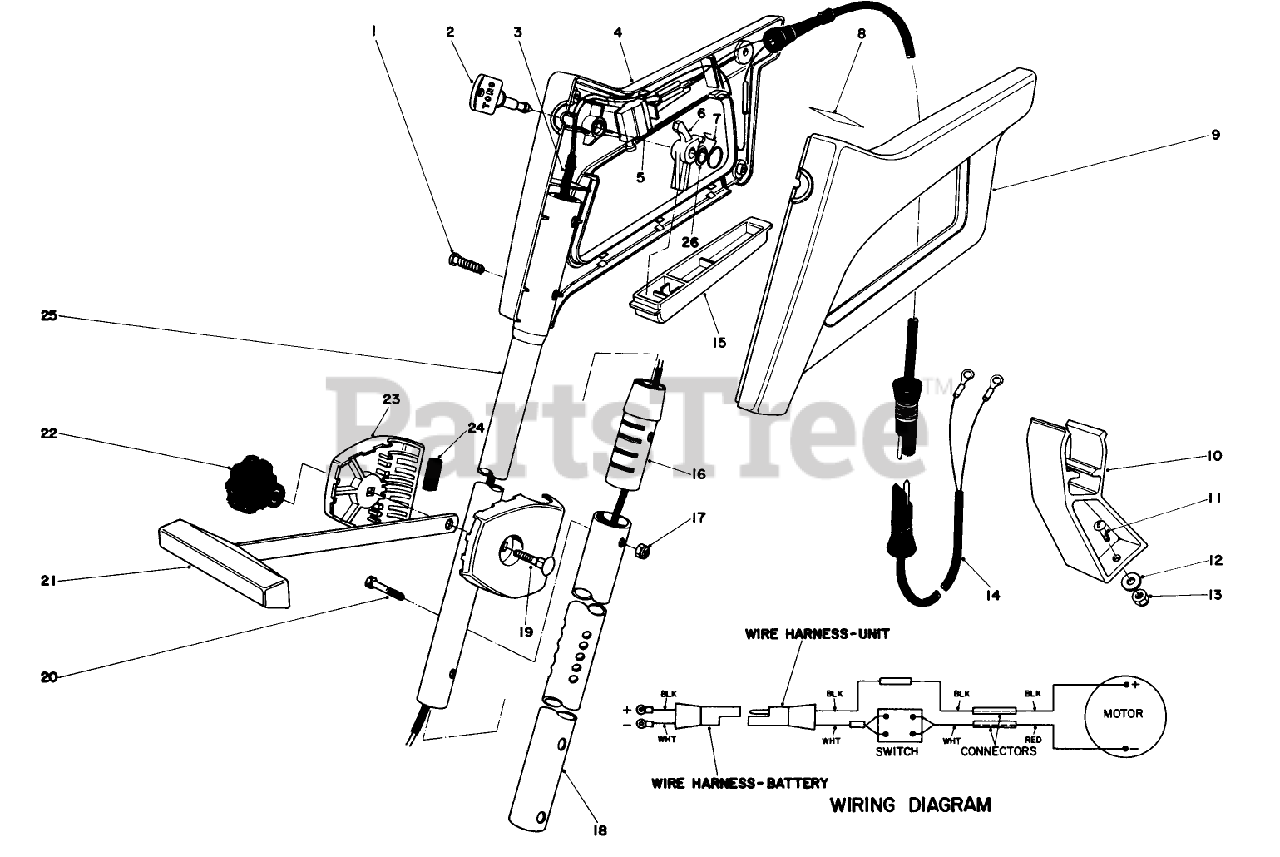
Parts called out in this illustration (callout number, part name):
1	SCREW-PPH
3	WIRE HARNESS
4	RT HALF CONT GRIP
5	SWITCH-STARTER
6	LOCKOUT
7	TORSION SPRING
8	Decal-12 Volt
9	LEFT HALF CONT GRIP
10	Trimmer Clip
11	SCREW-HH
12	WASHER-FLAT
13	NUT-LOCK, NI
14	Wire Harness-Battery
15	SWITCH BAR
16	Tubing Sleeve
17	NUT-LOCK, NI
18	Lower Tube
19	BOLT-CARR
20	Screw
21	Tee Handle
23	Clam Shell (Incl. Ref. #24)
24	RUBBER INSERT
25	Tubing-Upper
26	Eyelet
